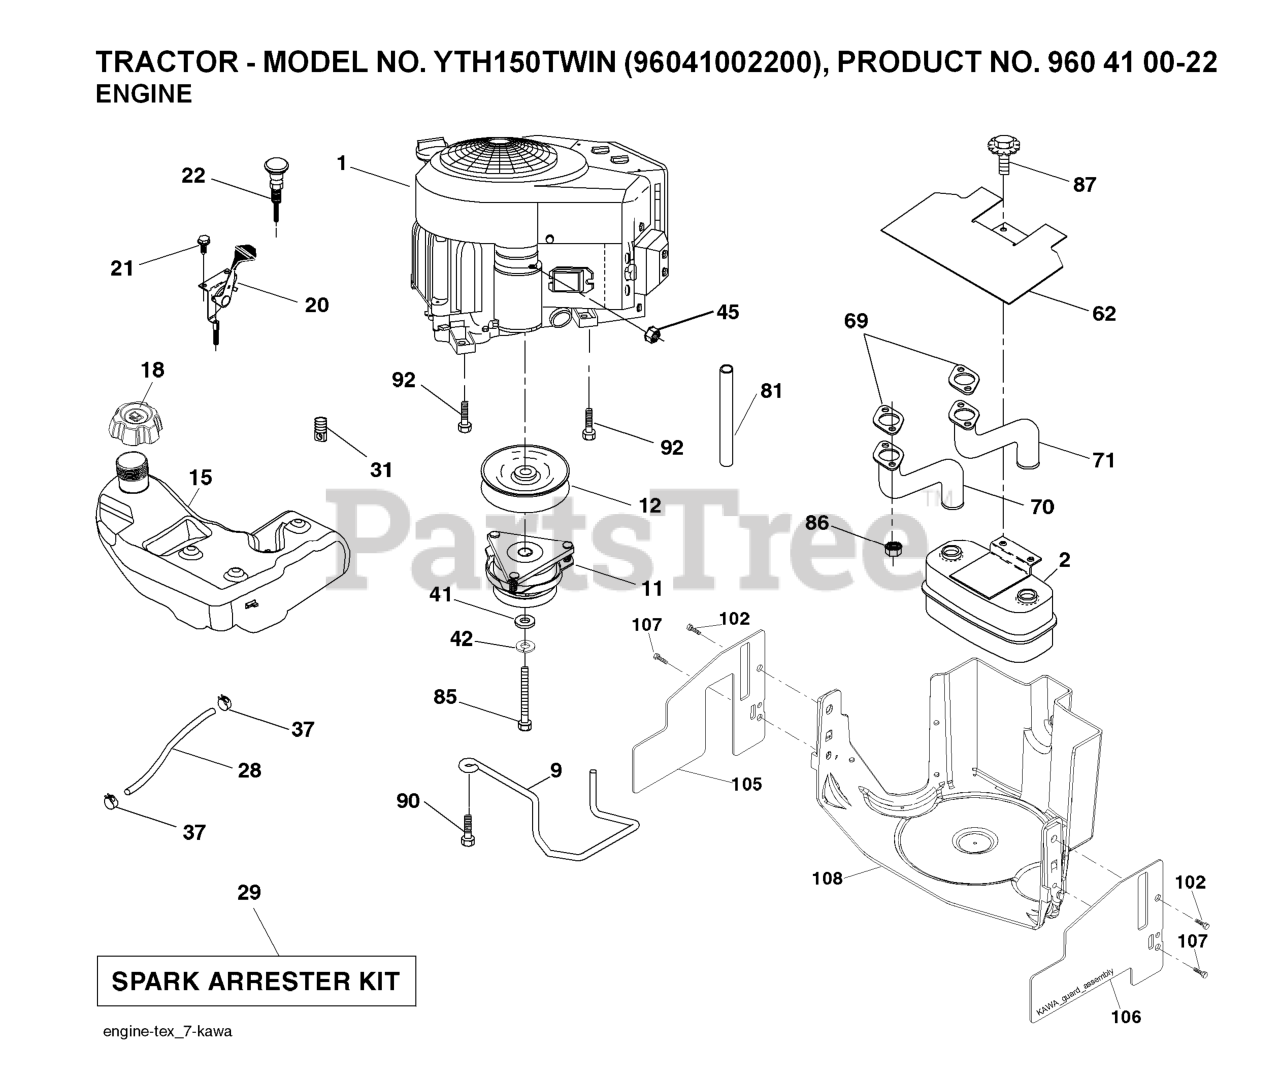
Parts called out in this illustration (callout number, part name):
2	MUFFLER.TWIN.CYL.LOW.TONE
9	KEEPER.BELT.ENGINE.3.25 (3 2)
11	RB.CLUTCH.OGURA.4.4.PD
12	PULLEY.ASM.ENG.OGURA.3
15	TANK.FUEL.4GAL
18	CAP.FUEL.TANK.3"GREY
20	THROTTLE CONTROL
21	SCREW
22	CONTROL, CHOKE
28	REPL BY 532 00 85-43
29	KIT.SPARK ARRESTOR 794945 B&S
37	HOSE CLAMP
42	LOCKWASHER
45	NUT
62	RP SHIELD HEAT MUFFLER
70	EXHAUST TUBE LH KAWI
71	EXHAUST TUBE RH KAWI
81	TUBE, DRAIN OIL ASM.
85	BOLT HEX 7/16-20X4-1/4"
86	NUT.HEX.FLANGE.TOPLOCK
87	BOLT.5/16-18UNCX1.W/SEMS.BLK
90	SCREW 3/8-16X1
92	SCREW 3/8-16X1
102	SCREW
105	SHIELD.SIDE.LH.3842"TEX FRENCH
106	SHIELD.SIDE.RH.3842"TEX FRENCH
107	SCREW.1/4-20X5/8
